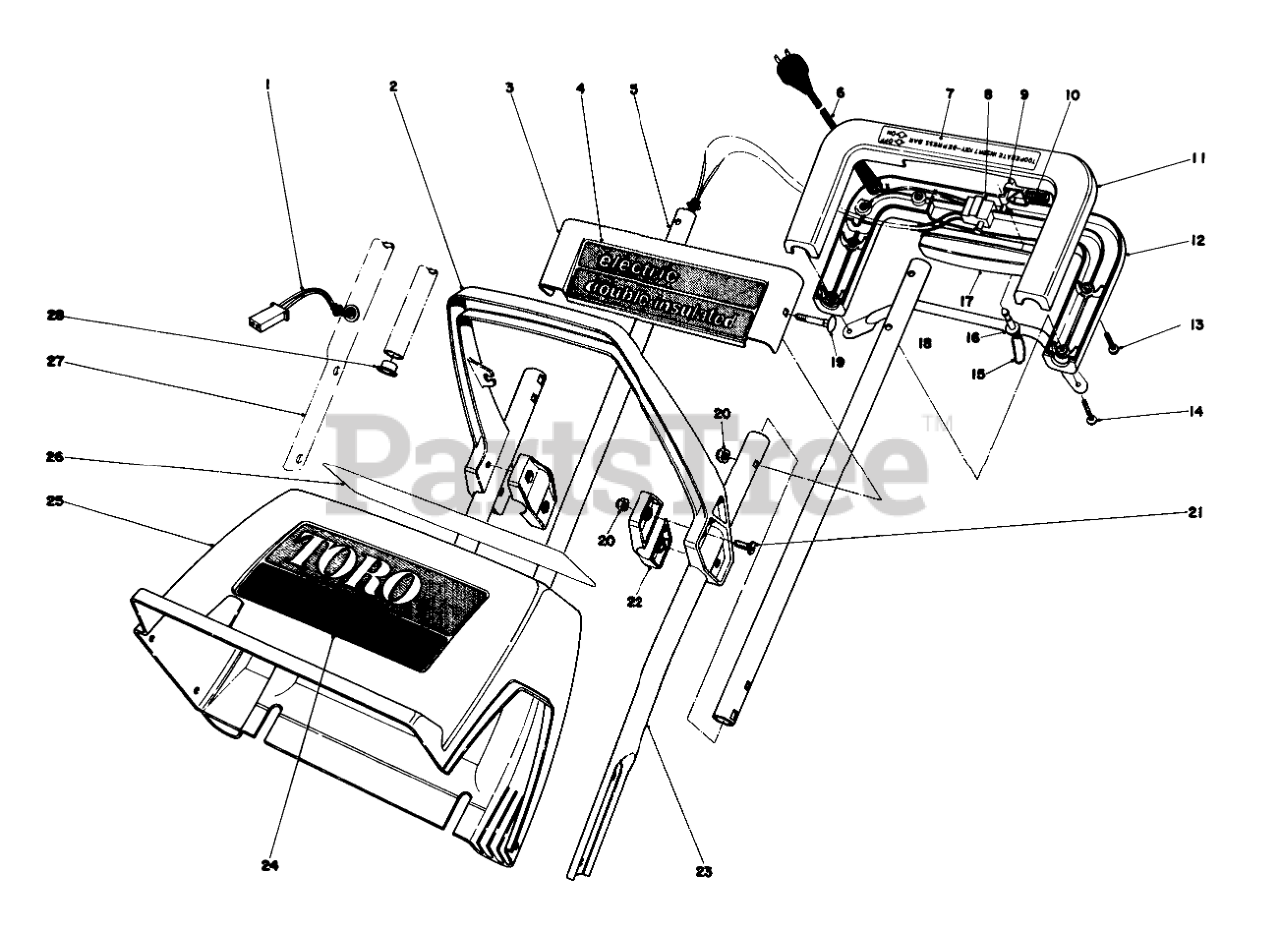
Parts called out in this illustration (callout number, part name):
1	Wire Harness
2	Middle Handle
3	Escutcheon Plate
4	Decal-Electric
5	Upper Tube
6	Cord Supply
7	Decal-Handle
8	SWITCH-STARTER
9	LOCKOUT, 1200
10	COMP SPRING
11	Handle-Upper Control
12	Handle-Lower Control
13	Screw
15	Key Chain
16	Key
17	SWITCH BAR, 1200 PC
18	Switch Guard
19	Bolt-Carriage
22	Clamp-Middle Handle
23	Handle-Lower L.H.
24	Decal-Toro S-120
25	Shroud S-120
26	Decal-U.L
27	Handle Lower R.H.
28	Snap Bushing
